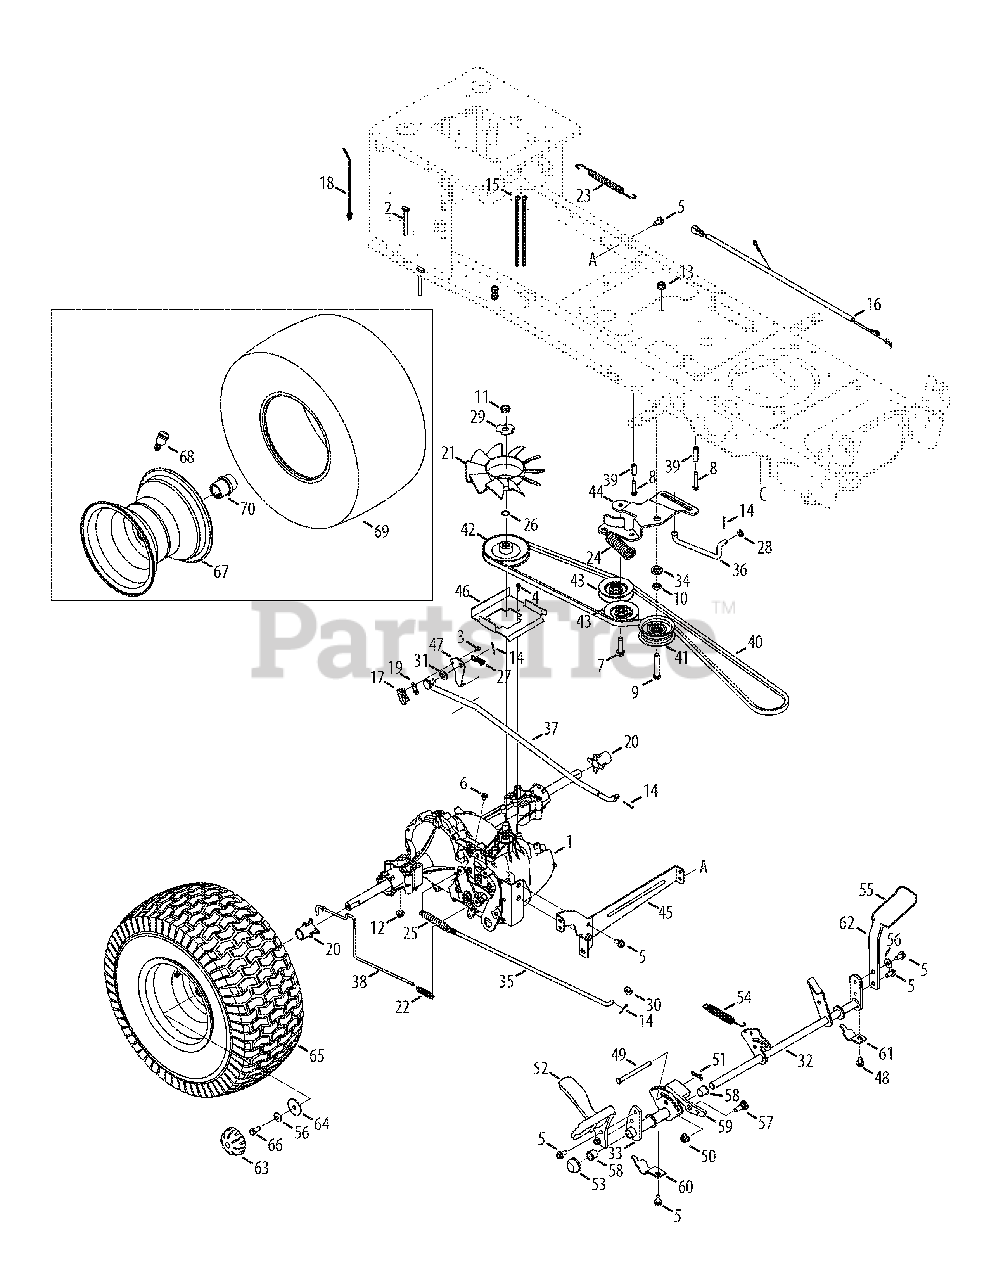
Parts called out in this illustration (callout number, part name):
1	Hydro Transmission
2	Hex Screw, 5/16-18:2.75
3	Screw, #8-18:0.500
4	Screw, #10-16:0.500
5	Taptite Screw, 5/16-18:.750
6	Taptite Screw, 1/4-20:0.375
7	Screw, Sems, 3/8-16, 1.500
8	Taptite Screw, 1/4-20:1.625
9	Hex Screw, 3/8-16:2.25
10	Jam Nut, 7/16-20
11	Nut, Jamlock, 1/2-20
12	Flangelock Nut, 5/16-18
13	Flangelock Nut, 3/8-16
14	Cotter Pin, 3/32:1.0
15	Cable Tie, 3/16 X .05 X 7.4
16	Jumper Harness
17	Short Spring Switch
18	Push Mount Cable Tie 7.5 LG
19	Insulator Nut Plate
20	Sleeve, .765 ID x 1.500 LG
21	Hydro Fan
22	Extension Spring, .48 OD X 2.03
23	Extension Spring, .500 DIA X 12.6 LG
24	Extension Spring, 1.00 DIA X 4.75
25	Extension Spring, .59 OD X 4.00 LG
26	Wire Ring
27	Extension Spring, .375 OD X 1.44 LG
28	Washer, Flat, .330 X .630 X .0635
29	Washer, Lock, TRANS HYDRO
30	Washer, Flat, .344 X .750 X .120
31	Washer, Flat, .407X.812X.135:HT
32	Brake Control Assembly
33	Hydro Pedal Bracket Assembly
34	Spacer, Shoulder, 1.375 X .380 X .183
35	Rod, Brake, Hydro
36	Rod, Transmission, Footpedal Bypass
37	Rod, Control, Hydro
38	Rod, Hydro Bypass
39	Spacer, .260 X .372 X 1.420 LG
40	Belt, V Type, Poly
41	Pulley, Idler, Flat 2.75 OD
42	Pulley, Input, 4.13 DIA
43	Pulley, Idler, V-Type x 3.06
44	Bracket, Idler, Center Double
45	Bracket, Mount, Hydro
46	Bracket, Support, Belt Disengage
47	Switch Actuator Bracket
48	Taptite Screw, 5/16-18:0.625
49	Clevis Pin, 5/16 x 3.985
50	Flangelock Nut, 3/8-16
51	Bow-Tie Cotter Pin
52	Control Pedal
53	Push Cap
54	Extension Spring, .63 DIA x 4.95 LG
55	Brake Pedal Pad
56	Washer, Bell, .340 x .872 x .060
57	Shoulder Bolt, .500 x .270:3/8-16
58	Flange Bearing, .630 ID x .695 OD x .60
59	Cruise Latch
60	Pedal Support Bracket
61	Pedal Support Bracket, 5/8
62	Brake Pedal Bracket
63	Hub Cap
64	Washer, Flat, .350 x 1.59 x .062
65	Wheel Assembly
66	Hex Screw, 5/16-24 x .750
67	Rim Assembly
68	Tubeless Air Valve
70	Axle Hub
